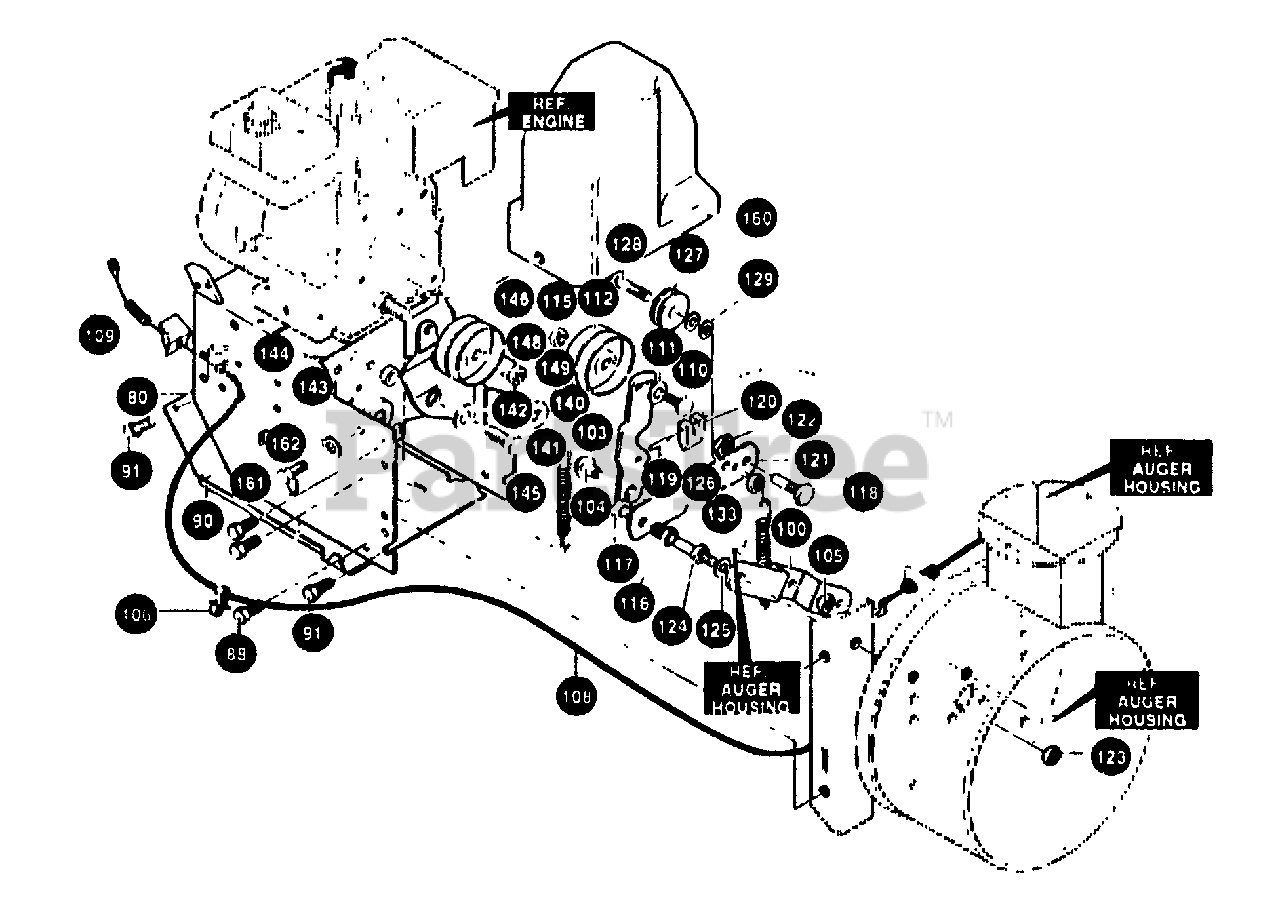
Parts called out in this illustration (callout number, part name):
80	FRAME, ASSY
88	SCREW, 5/16-18X .50
90	COVER, BOTTOM
91	SCREW, 1/4-20X .63
100	PLATE, CLUTCH ARM
103	BRACKET, IDLER
104	BOLT, HHSH 3/8-16
105	NUT, 3/8-16 CTRLK
106	CLIP, CABLE
108	CABLE, AUGER
109	SHIELD, CABLE GUARD
110	C. BOLT, 3/8-16X1.25
111	FLATWASHER
112	PULLEY, IDLER
115	NUT, 3/8-16
116	BOLT, BRAKE ARM
117	NUT, 9/16-18 JAMCTRLK
118	BOLT BRAKE ARM
119	SPRING PIN
120	PAD, AUGER/IMP
121	BRACKET PUCK
122	NUT. 1/2-20 JAMCTRLK
123	NUT, 3/8-16 RGHXCTRLK
124	STUD. BRAKE ARM
125	WASHER, REGSPTLK
126	NUT, 1/4-20 RGHXCTRLK
127	PULLEY, METAL
128	BOLT, SH 1/4-20
129	FLATWASHER
133	SPRING, IDLER BRAKE
140	LEVER, IDLER ARM
141	SCREW, 5/16-18X .75
142	WASHER. FLAT .328X1.25X.075
143	BUSHING, IDLER LEVER
144	NUT, 5/16-18 HEXNYL
145	IDLER SPRING
146	SCREW, 3/8-16X1.25
148	PULLEY, IDLER
149	NUT, 3/8-16
160	COVER. BELT
161	SCREW, 1/4-20X .63
162	WASHER. FLAT .281X .63X.065
